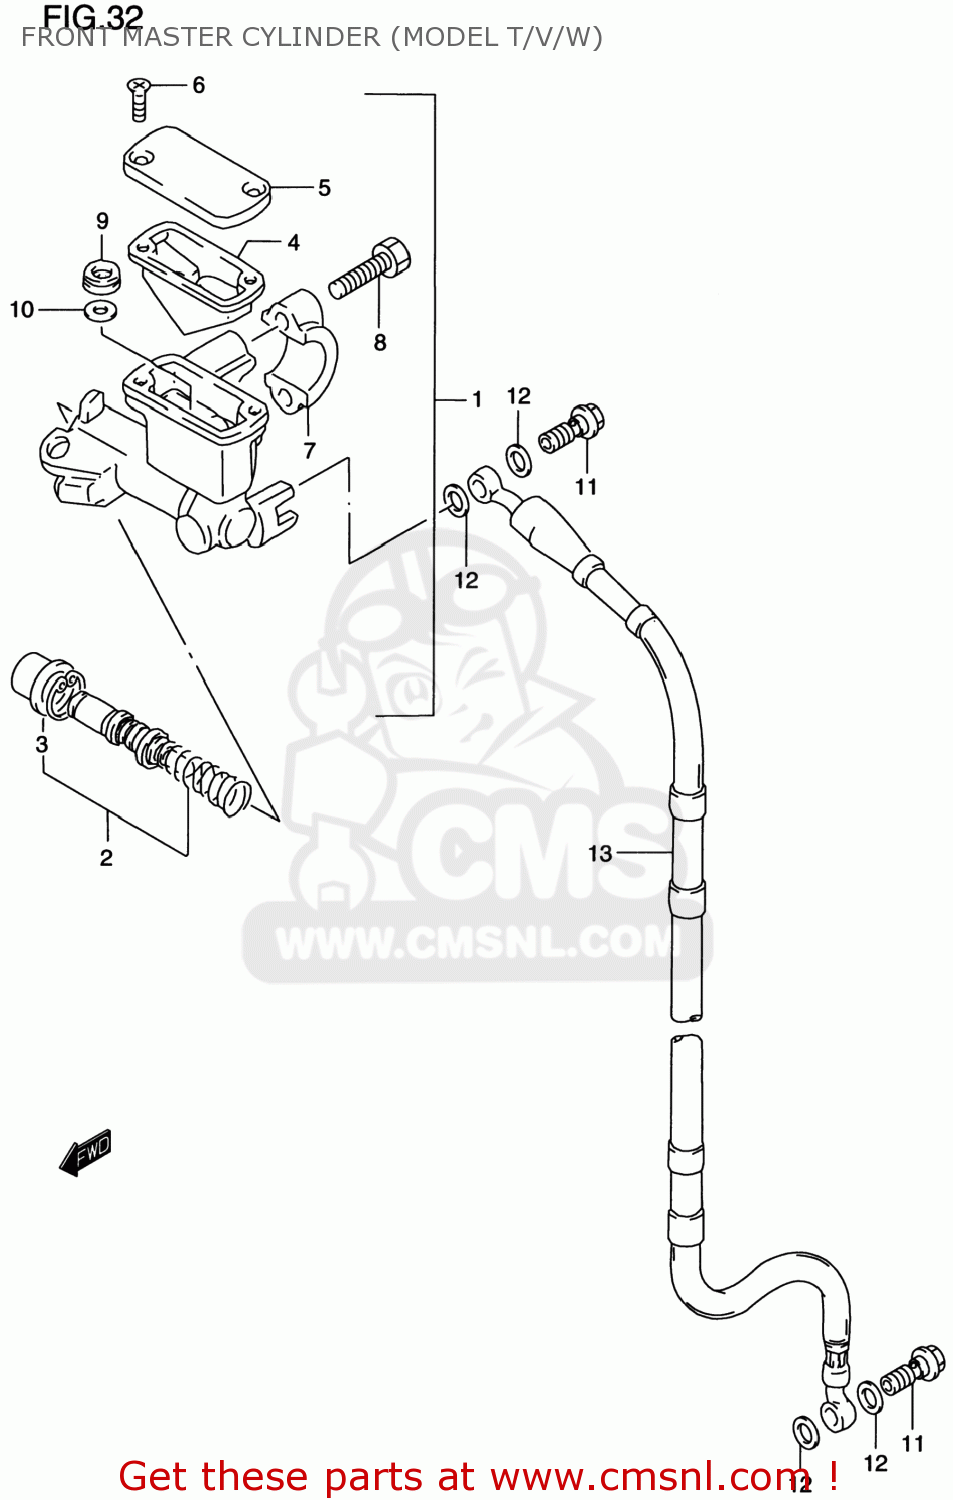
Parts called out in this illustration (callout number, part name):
1	CYLINDER ASSY,FR MASTER
2	PISTON & CUP SET
3	BOOT
4	DIAPHRAGM
5	CAP
6	SCREW
7	HOLDER
8	BOLT
9	SEPARATOR
10	RING
11	BOLT UNION
12	WASHER(10X15X1.5)
13	HOSE COMP,FRONT BRAKE
